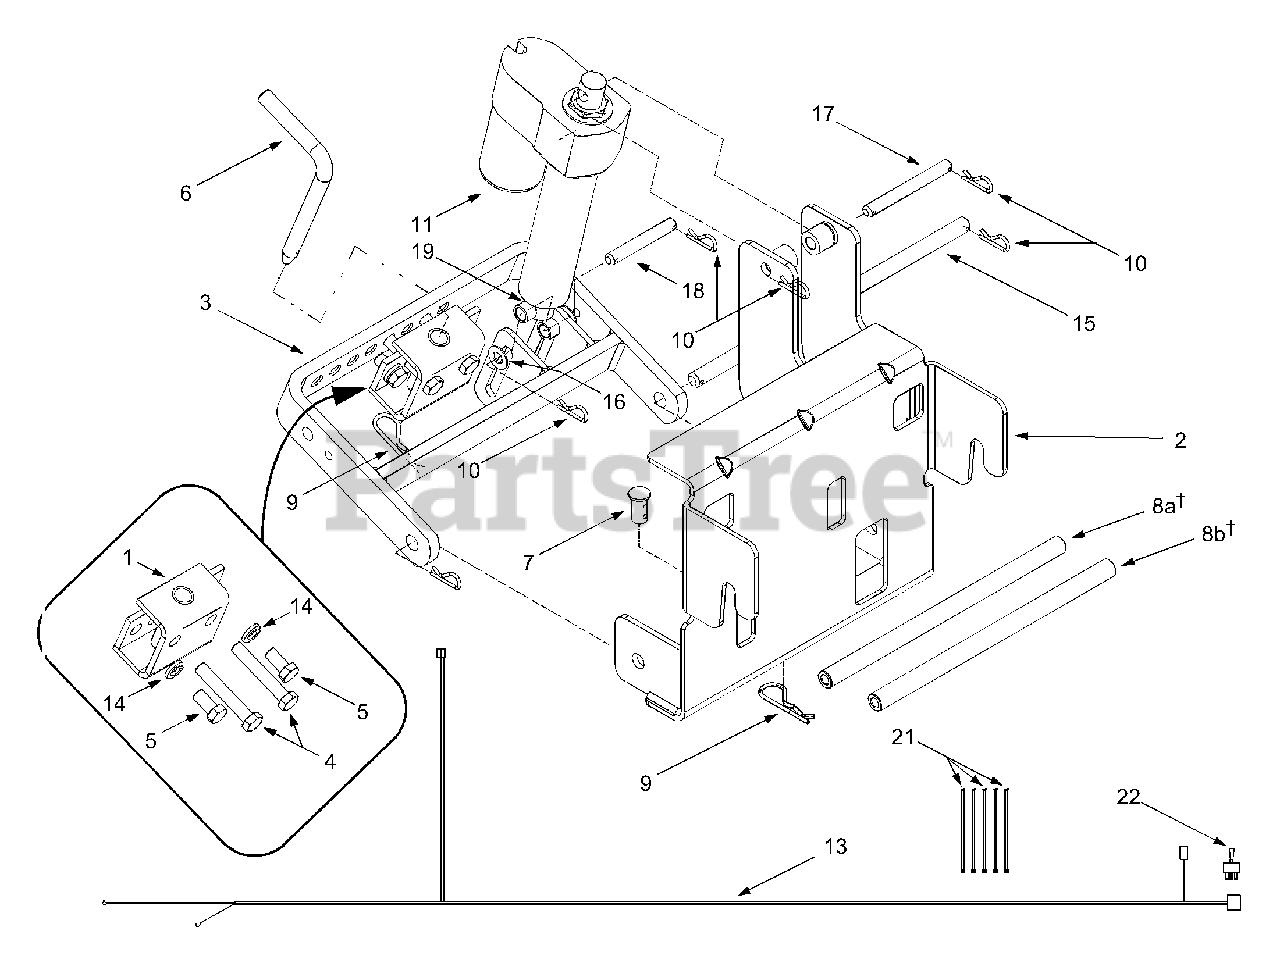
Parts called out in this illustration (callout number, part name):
1	Hitch Bracket Assembly
2	Sleeve Hitch Bracket Assembly
3	Sleeve Hitch Assembly
4	Hex Cap Screw, 1/2-13 x 3 (Grade 5)
5	Hex Cap Screw, 1/2-13 x 1 (Grade 5)
6	Hitch Pin
7	Clevis Pin
8A	Support Rod, 3/4 x 13" ( 7/16-20)
8B	Support Rod, 3/4 x 13" (3/8-16)
9	Internal Cotter Pin, .148 x 3
10	Internal Cotter Pin
11	Electromechanical Linear Actuator
12	Flat Washer, .51 x 1.0 x .06
13	Wire Harness
14	Lock Washer, 1/2
15	Hitch Rod
16	Flat Washer, .51 x 1.12 x .060
17	Upper Cylinder Support Rod
18	Lower Cylinder Support Rod
19	Spacer, .542 x .750 x .5
22	Toggle Switch
